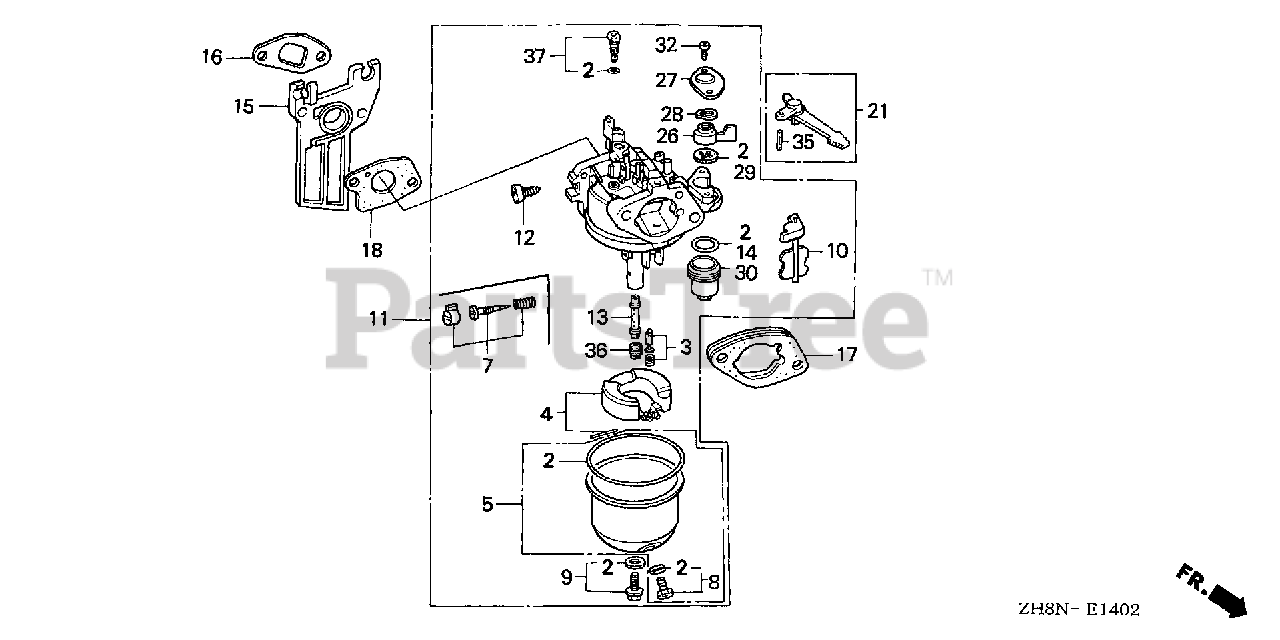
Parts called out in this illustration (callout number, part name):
2	GASKET SET
3	VALVE SET, FLOAT
4	FLOAT SET
5	CHAMBER SET, FLOAT
7	SCREW SET
8	SCREW SET, DRAIN
9	SCREW SET B
10	CHOKE SET
11	CARBURETOR ASSY. (BE65B B)
12	SCREW, THROTTLE STOP
13	NOZZLE, MAIN
14	GASKET, FUEL STRAINER CUP
15	INSULATOR, CARBURETOR
16	GASKET, INSULATOR
17	SPACER, CARBURETOR
18	GASKET, CARBURETOR
21	LEVER, CHOKE (STD)
26	LEVER, VALVE
27	PLATE, LEVER SETTING
28	SPRING, VALVE LEVER
29	GASKET, VALVE
30	CUP, FUEL STRAINER
32	SCREW, PAN (3X6)
35	PIN, SPRING (2X12)
36	JET, MAIN (#65)
36	JET, MAIN (#68)
36	JET, MAIN (#70)
37	JET SET, PILOT (#35)
